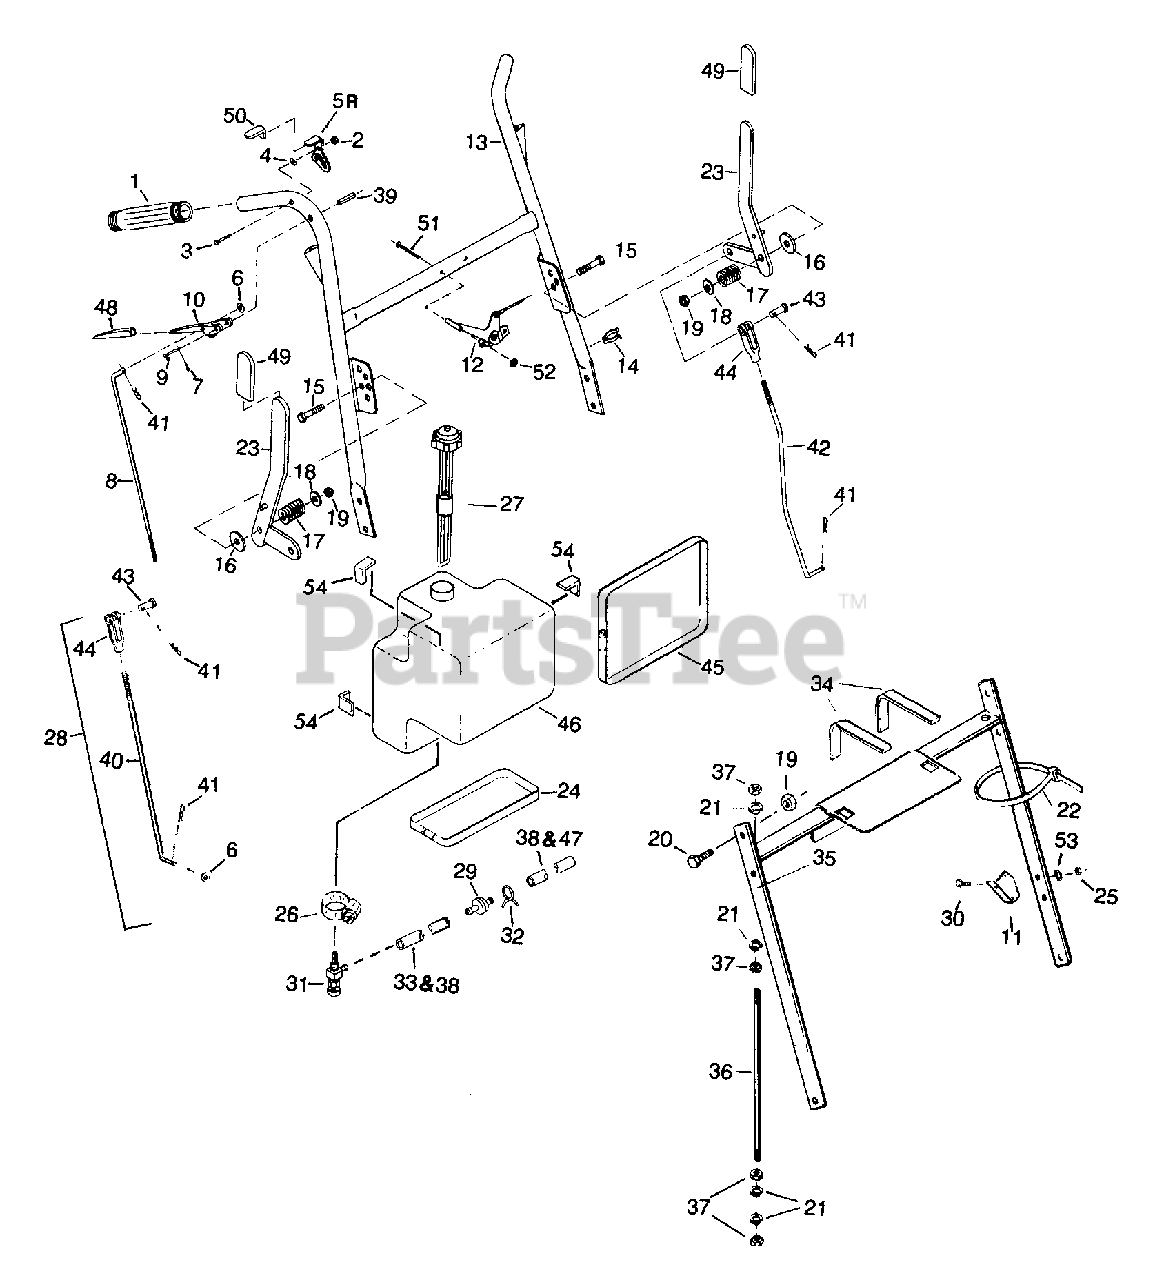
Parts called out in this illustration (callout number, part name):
1	Handle Grip
2	1/4"-20 Prevailing Torque Nut
3	1/4"-20x1-1/2" Hex Hd. Cap Screw
4	1/4" Dia. Wavy Spring Washer
5R	Right Thumb Latch w/Grip (P/N 76527)
6	5/16" Std. Flat Washer
7	3/32"x1/2 Cotter Pin
8	Drive Linkage
9	3/16" Clevis Pin
10	Drive Lever w/Grip (P/N 76525)
11	Interlock Bracket-Blade Drive
12	Throttle Control, Complete
13	Upper Handle w/Decals
14	1" Cable Clip
15	3/8"-16x2" Hex Hd. Cap Screw-Grade 5
17	Compression Spring
18	3/8" Std. Flat Washer
19	3/8"-16 Nyloc Hex Nut
20	3/8"-16x1" Hex Hd. Cap Screw-Grade 5
21	1/2" Lock Washer
22	Plastic Tie
23	Lever Assy Complete w/Grip (P/N 76526)
24	Tank Band-Short
25	1/4"-20 Nyloc Hex Nut
26	Hose Clamp
27	Gas Cap w/Gauge
28	Ground Speed Linkage Kit
29	Gas Filter
30	1/4"-20x3/4" Hex Hd. Cap Screw-Grade 5
31	Gas Line Shut Off
32	Gas Line Clamp
33	Gas Line Hose-17-1/2" Long (Briggs & Stratton Only)
34	Saddle Pad
35	Lower Handle
36	Handle Brace
37	1/2"-13 Regular Hex Nut
38	Gas Line Hose (Kawasaki Only)
39	5/16" x 1" Roll pin
40	Ground Speed Linkage
41	#2 Hairpin Cotter
42	Upper Blade Drive Linkage
43	5/16" Clevis Pin
45	Tank Band-Long
46	4 Gal. Gas Tank w/Decals
47	Gas Line Hose 3-1/2" Long (Briggs & Stratton Only)
48	Drive Lever Grip
49	Adjustment Lever Grip
50	Thumb Latch Grip
51	#10-24x1-1/2" Rd. Hd. Slt. Mach. Screw
52	#10-24 Nyloc Hex Nut
53	Internal Tooth Lock Washer
54	Gas Tank Pad
